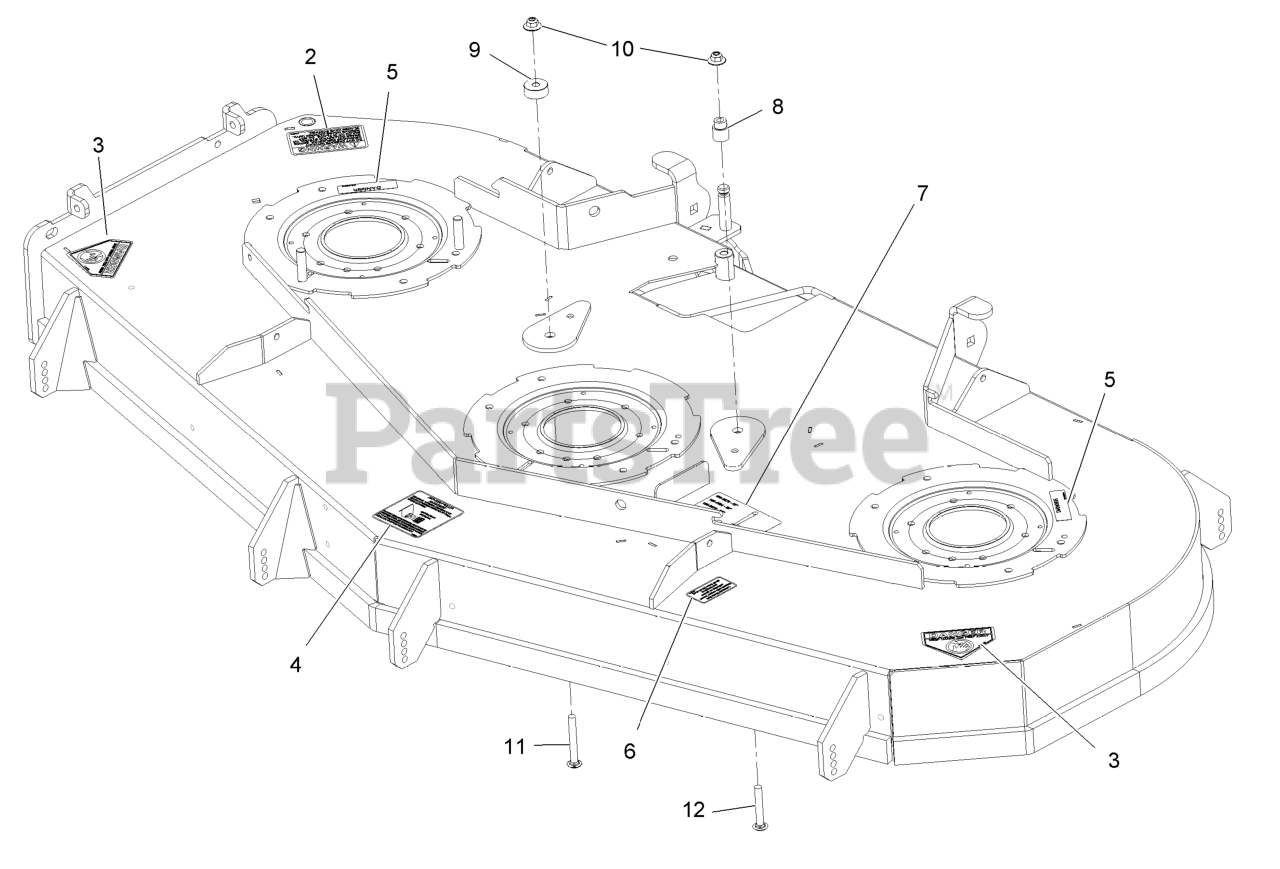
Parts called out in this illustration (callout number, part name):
2	DECAL-WARNING, DISCHARGE
3	DECAL-DANGER
4	DECAL,ANTISCALP
5	DECAL-COVER, MISSING
6	DECAL,BOLT TORQUE
7	DECAL,BELT ROUTING
8	BUSHING-IDLER
9	SPACER-IDLER
10	Nut-Nyloc 3/8-16 Flg
11	SCREW-CARR
12	SCREW-CARR
